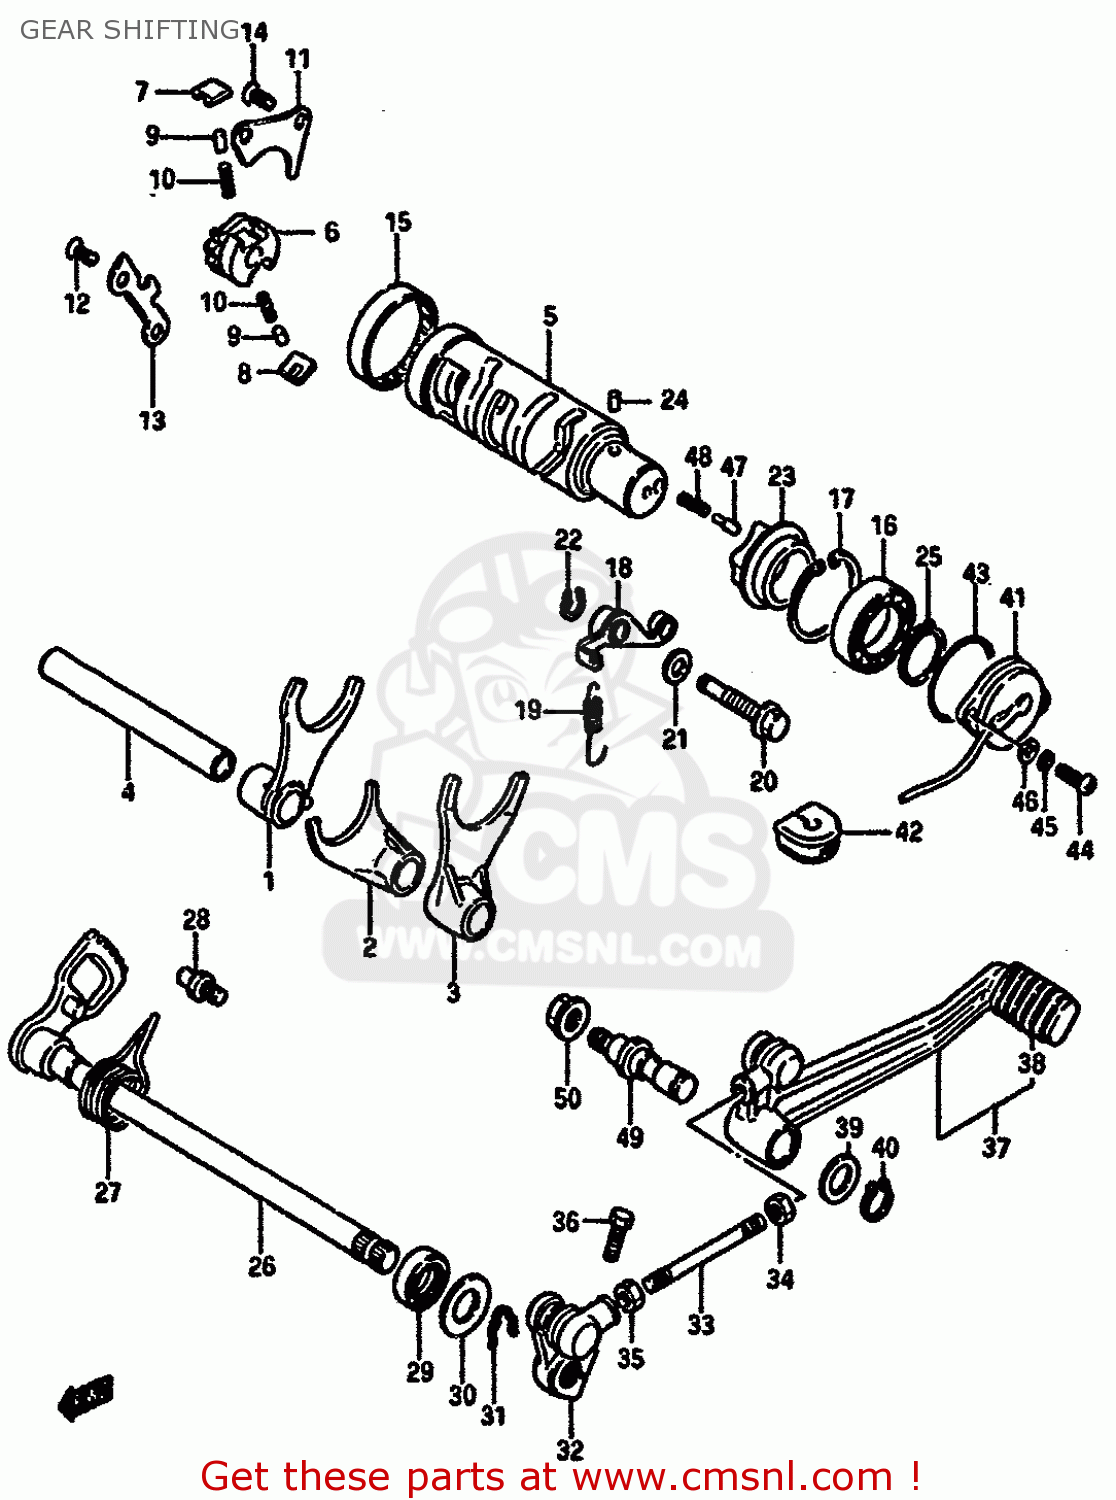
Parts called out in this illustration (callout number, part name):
1	FORK,GEAR SHIFT NO.1
2	FORK,GEAR SHIFT NO.2
3	FORK,GEAR SHIFT NO.3
4	SHAFT,GEAR SHIFT FORK(L:128)
5	CAM,GEAR SHIFT
6	GEAR,GEARSHIFT CAM DRIVE
7	PAWL,GEAR SHIFT NO.1
8	PAWL,GEAR SHIFT NO.2
9	PIN(5X8)
10	SPRING
11	LIFTER,GEAR SHIFT PAWL
12	SCREW
13	GUIDE,GEAR SHIFT CAM
14	SCREW
15	BEARING(43X49X12)
16	BALL BEARING
17	CIRCLIP,42MM
18	STOPPER,GEAR SHIFT CAM
19	SPRING
20	SHAFT,GEAR SHIFT CAM STOPPER
21	GASKET(10X14X3.6) (NAS)
22	CIRCLIP
23	PLATE,STOPPER
24	PIN 4X6
25	CIRCLIP,25MM
26	SHAFT,GEAR SHIFT
27	SPRING
28	STOPPER,GEAR SHIFT CAM
29	OIL SEAL
30	WASHER (12.5X27X1.6)
31	SPRING,RETAINER
32	ARM,GEAR SHIFT
33	ROD,GEAR SHIFT LINK
34	NUT
35	NUT 6MM
36	BOLT
37	LEVER ASSY,GEAR SHIFT
38	RUBBER,BRAKE PEDAL
39	WASHER(12.5X20X1)
40	CIRCLIP
41	TERMINAL BASE,NEUTRAL SWITCH
42	GROMMET,LEAD WIRE
43	O RING(D:2.4,ID:36.5)
44	SCREW(5X14)
45	LOCK WASHER
46	WASHER
47	PIN(5X15.5)
48	SPRING
49	SHAFT,GEAR SHIFT LEVER
50	NUT
